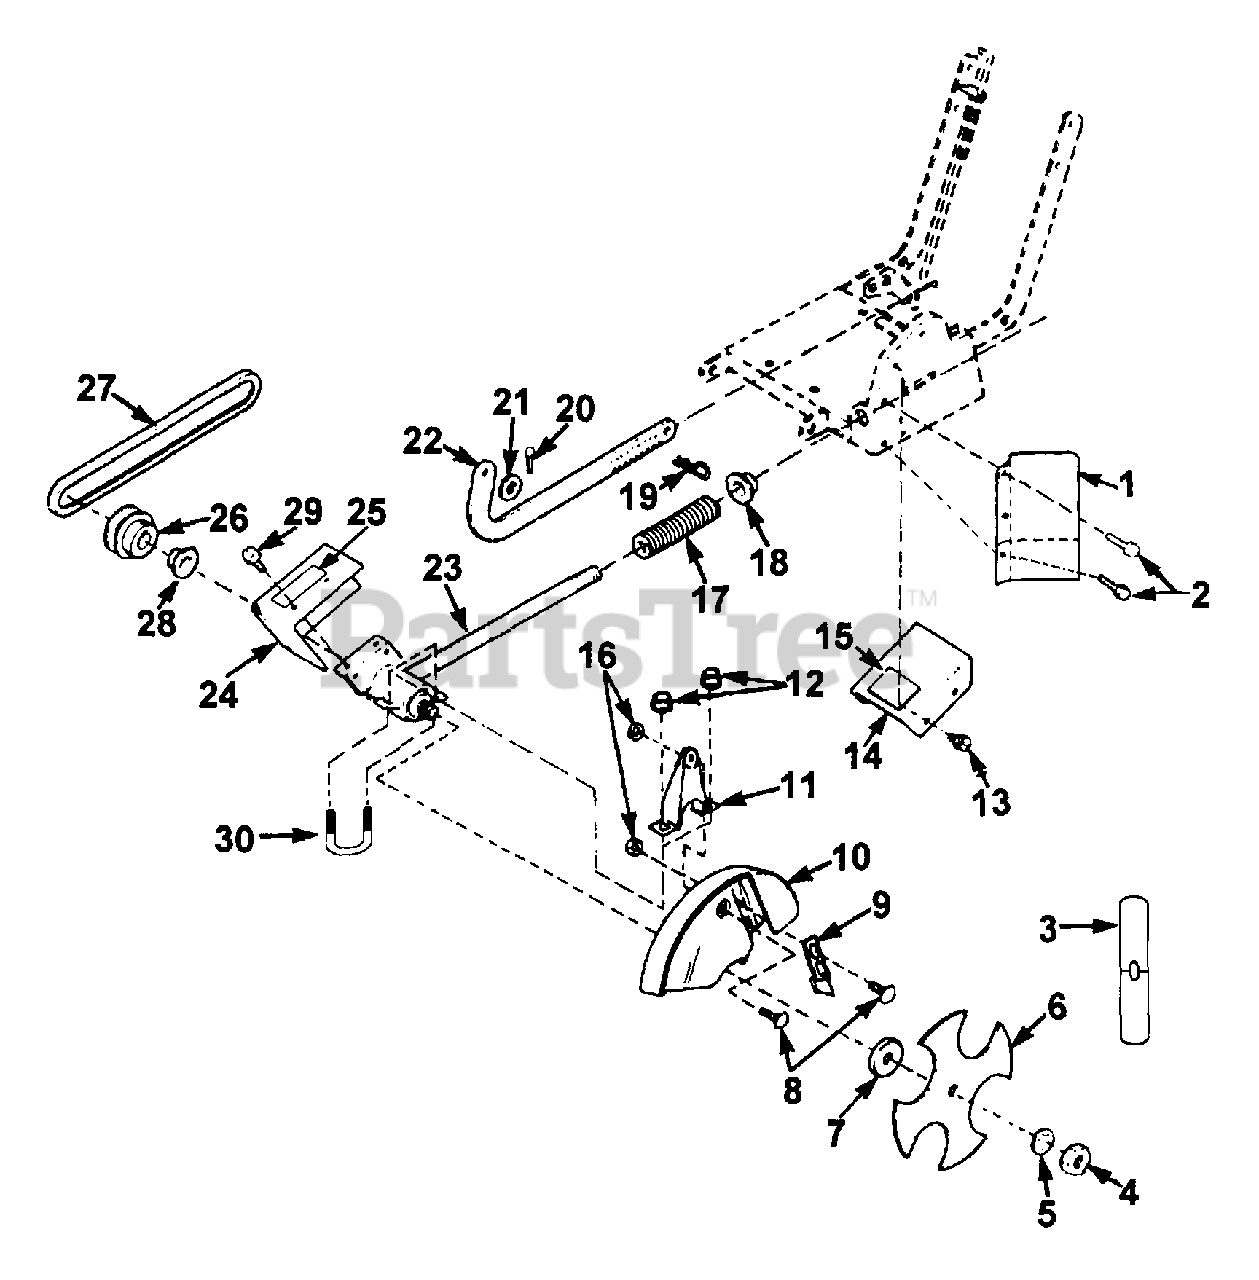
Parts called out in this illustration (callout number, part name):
1	Flap (Debris Shield)
2	Screw (1/4-20 x 1/2")
3	Blade (2" x 9")
4	Nut (Jam 5/8 x 18)
5	Washer (Lock 5/8")
6	Blade (Star)
7	Washer (Dust Shield)
8	Bolt (Carriage 1/4" x 5/8")
9	Finger (Guide)
10	Guard (Blade)
11	Bracket (Blade Support)
12	Nut (Flanged 5/16-18)
13	Screw (1/4-20 x 1/2")
14	Guard (Engine Pulley)
15	Decal (Safety)
16	Nut (1/4-20)
17	Spring (Cutter Head)
18	Bushing (Nylon 3/4")
19	Cotter Pin
20	Cotter Pin
21	Washer (Flat)
22	Ratchet (Depth Control)
23	Gear Head
24	Guard (Cutter Pulley)
25	Decal (Warning)
26	Pulley (Cutter)
27	Belt (3/8 x 29")
29	Screw (1/4-20 x 1/2")
